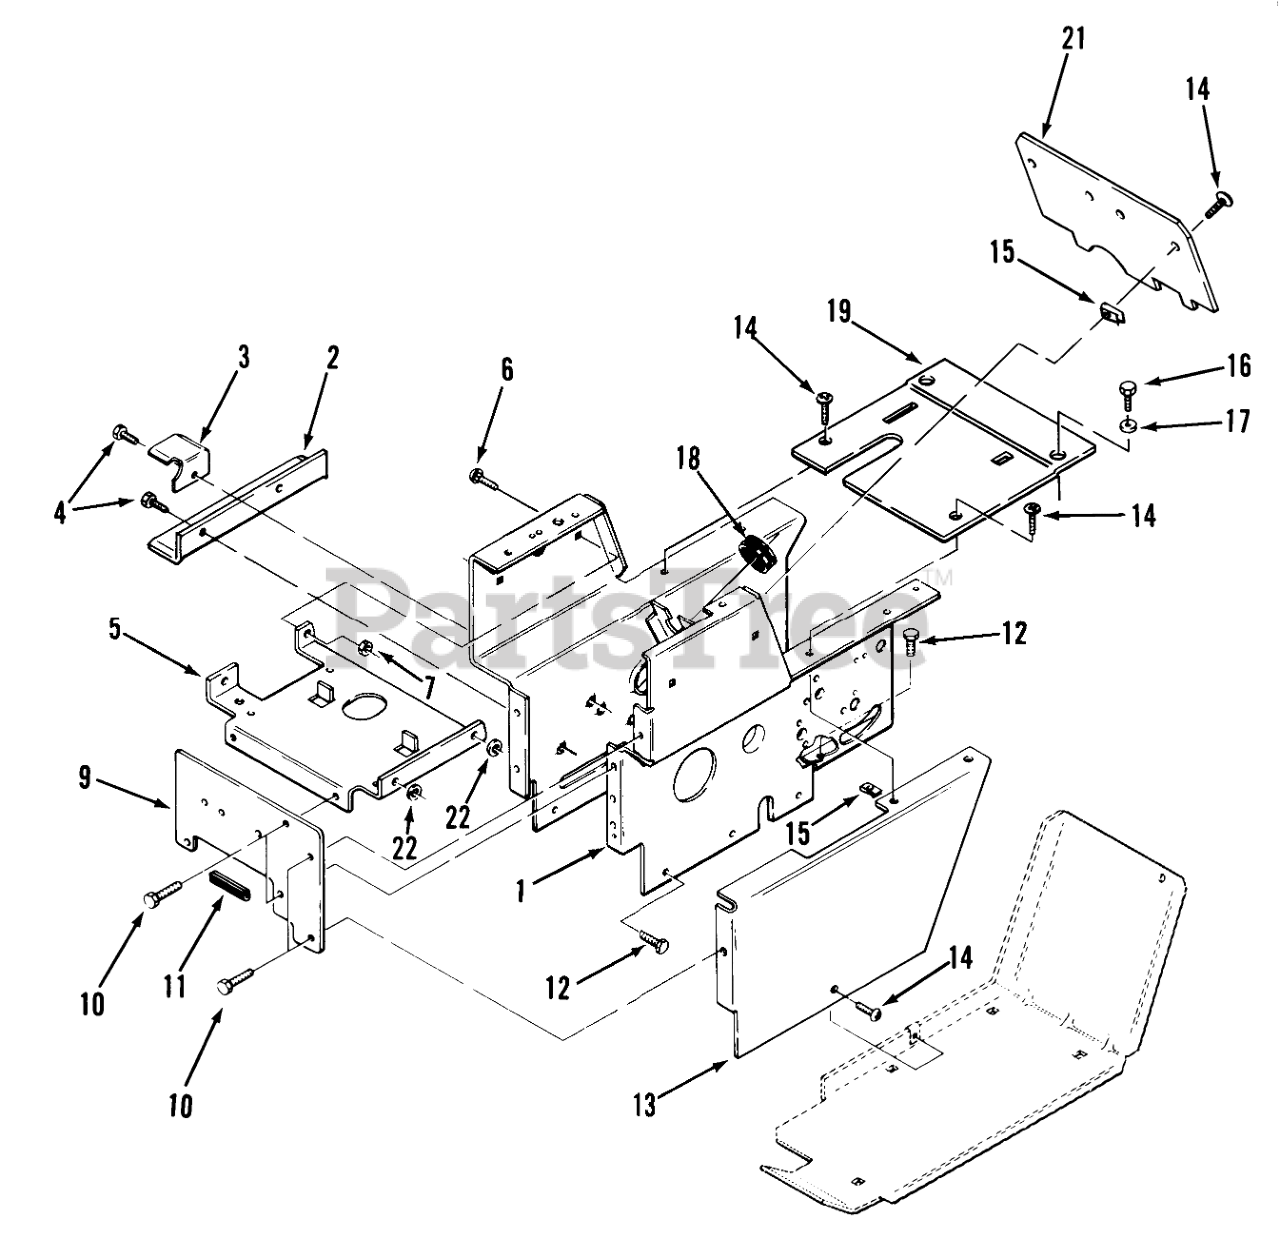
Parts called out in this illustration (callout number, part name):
1	Hoodstand
2	ANGL-BLT GURDB
3	BRCKET-BLT SUTB
4	SCREW
5	Battery Support Bracket
6	CARRIAGE BOLT -4
7	Nut
9	Front Plate
10	SCREW
11	EDGE TRIM 2" 102896
12	SCREW
13	Side Cover LH
14	Screw
16	HHCS
17	Lockwasher
18	GROMMET
19	PLATE - SHIFT
21	Hood Stand Plate
22	Washer
